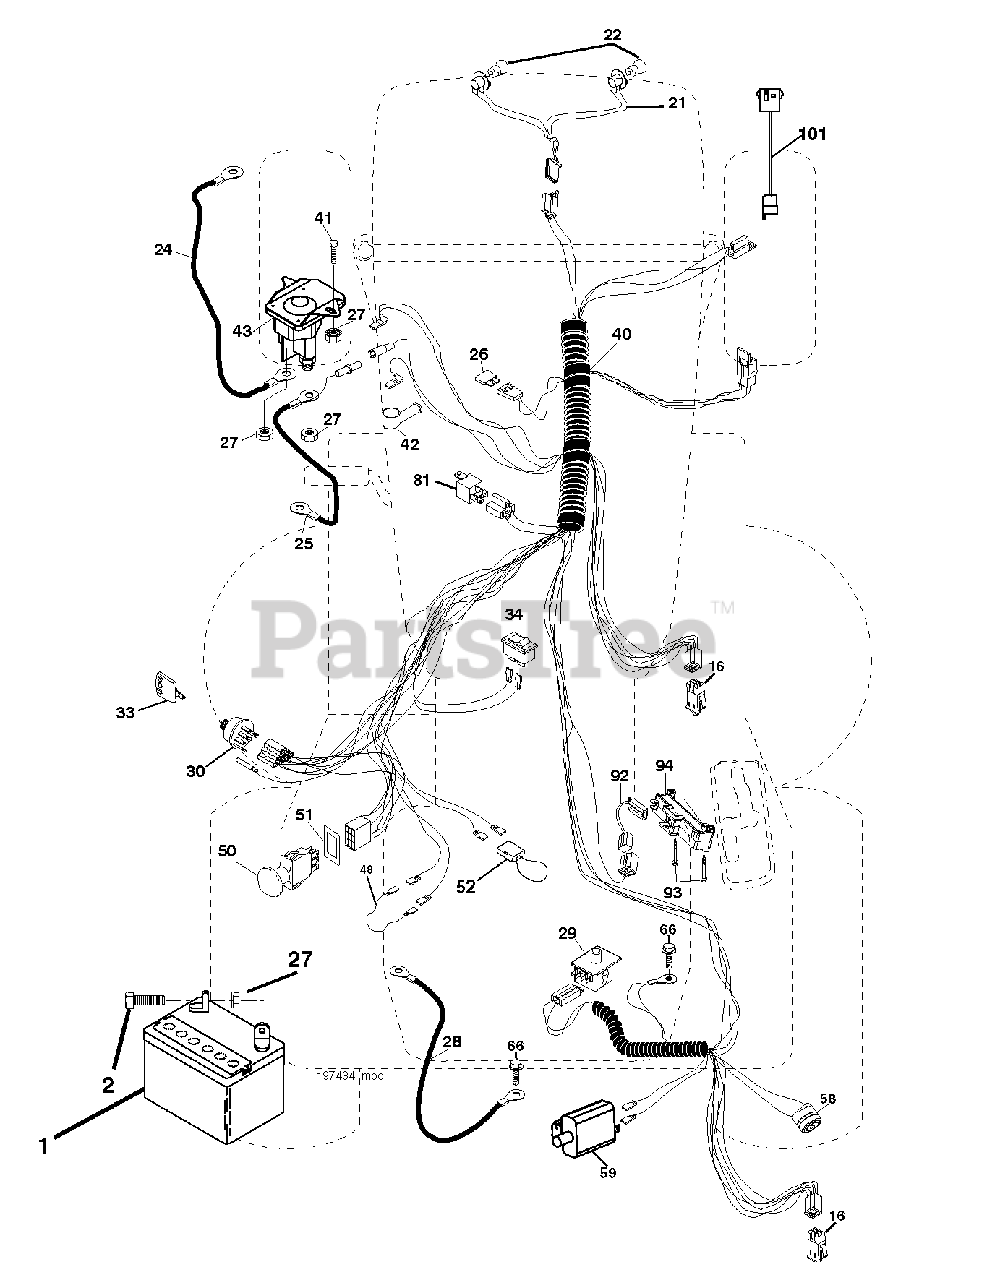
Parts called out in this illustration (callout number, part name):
1	BATTERY 12V .35 AMP
16	SWITCH INTERLOOK PUSH-IN
21	HARNESS ASSY LIGHT
22	LIGHTBULB
24	BATTERY CABLE GT
25	CABLE BATTERY
26	FUSE 20AMP
27	NUT
28	CABLE GROUND
29	SWITCH.SEAT.DP W/RAMPS
30	SWITCH.IGN.DELTA.W.LGH.ROS
33	KEY MLD GEN DELTA
34	SWITCH LT
42	TERMINAL COVER
43	SOLENOID.W/BRASS.PLUNG
50	PTO SWITCH
51	RETAINING RING
52	WIRE PROTECTION LOOP
58	BUZZER
81	RELAY.ASSY.T
92	HARNESS.PIGTAIL.CONSLE
93	SCREW.PLASTITE
94	MODULE.REVERSE.ROS
101	PIGTAIL.MATNLK.NEW.HAR
